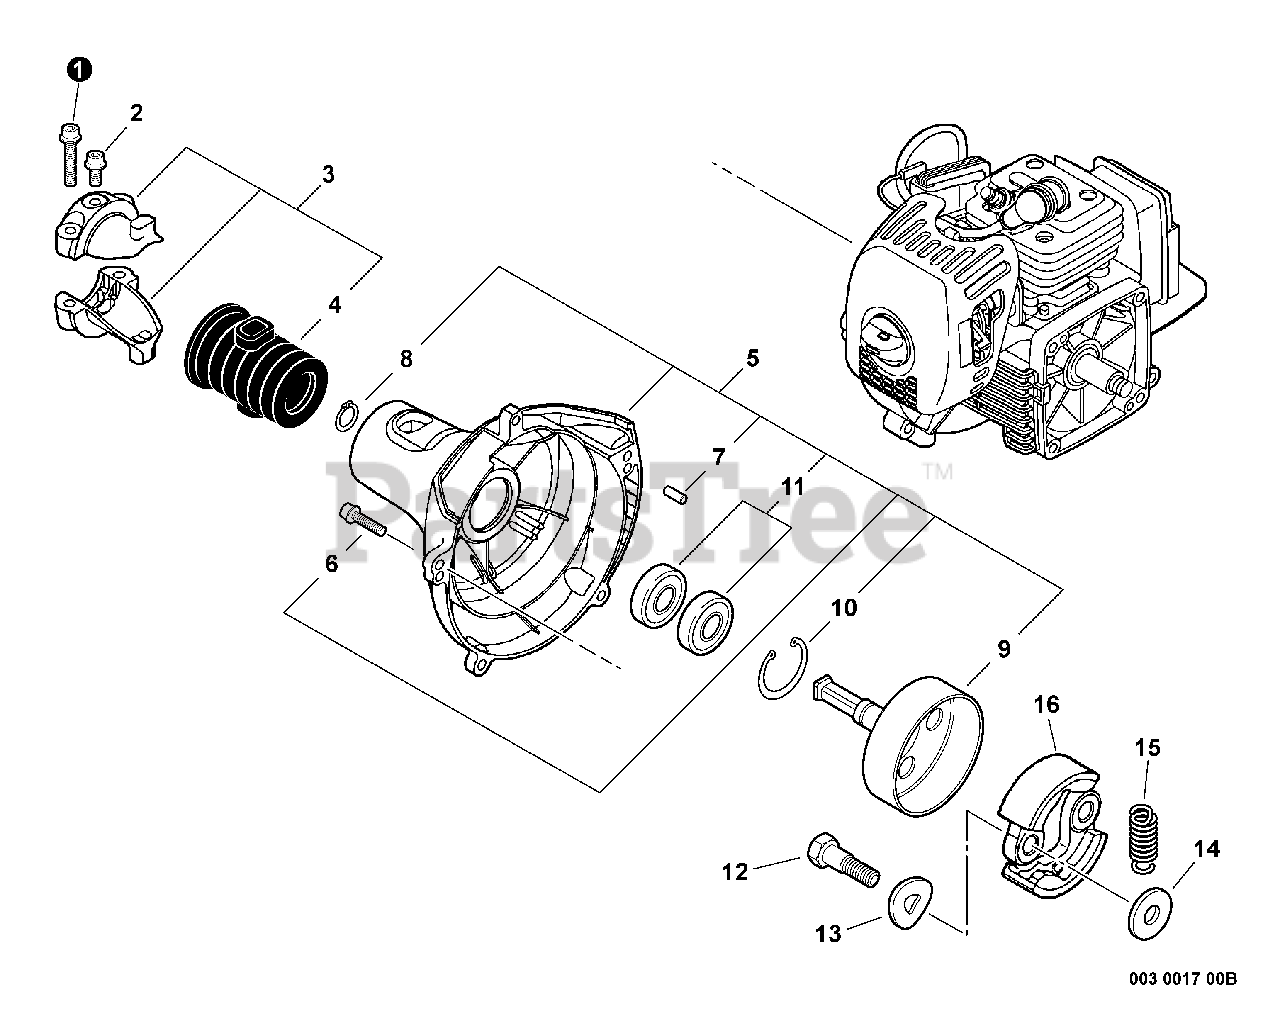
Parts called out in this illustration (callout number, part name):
1	SCREW - 5X25
2	SCREW - 5X10
3	MAIN PIPE CLAMP KIT
4	CUSHION
5	FAN CASE ASSY
6	SCREW - 5X20
7	PIN - LOCATING
8	RING, RETAINING - 12
9	DRUM, CLUTCH
10	RING, RETAINING - 28
11	BEARING, BALL - 6001
12	BOLT, CLUTCH
13	WASHER - SPRING
14	WASHER - 6
15	SPRING, CLUTCH
16	SHOE, CLUTCH
